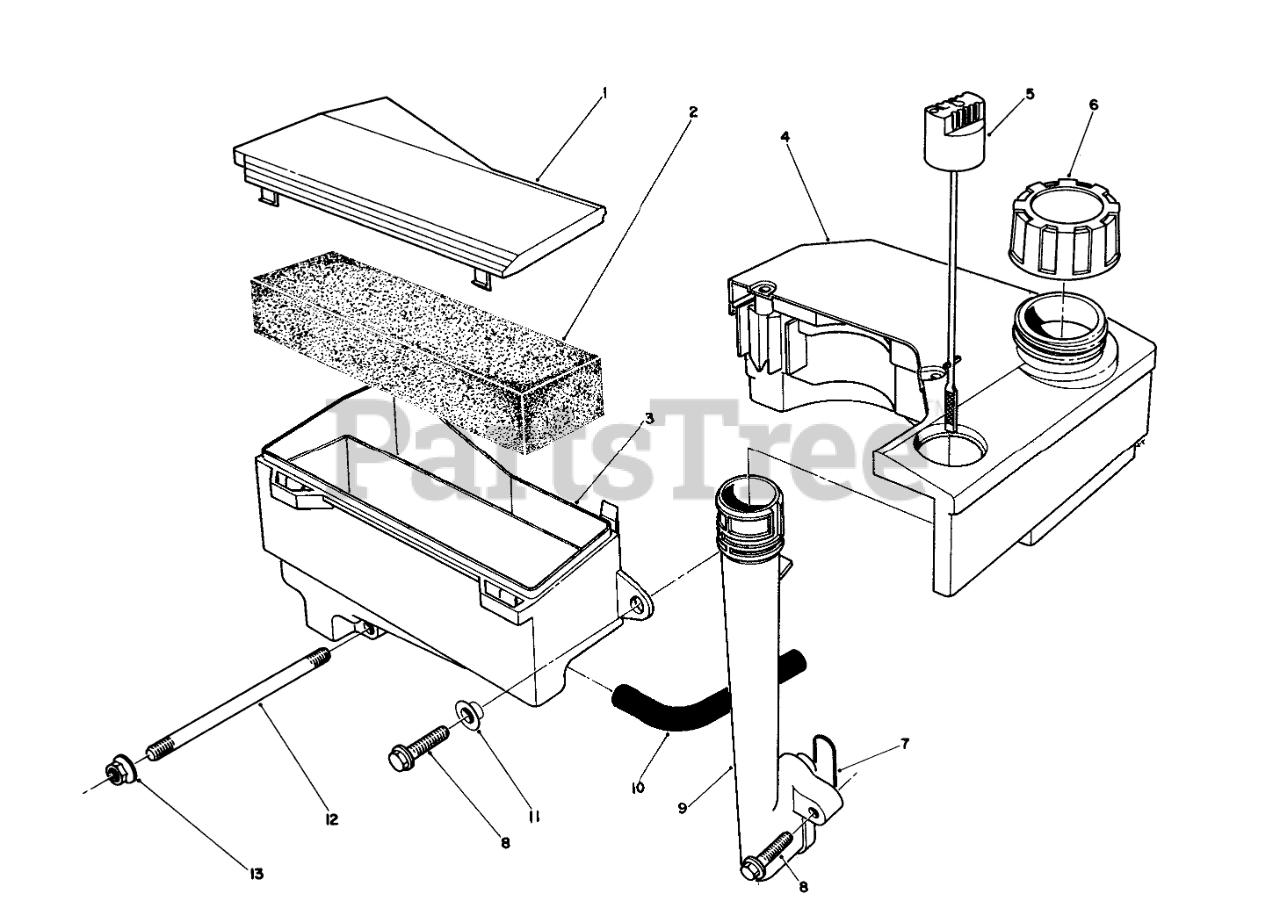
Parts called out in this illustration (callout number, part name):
1	AIR CLEANER CAP
3	Body-Air Cleaner
4	TANK ASM
5	Dipstick
6	GAS CAP ASM
7	O-RING
11	SPACER
12	Stud-Carburetor
